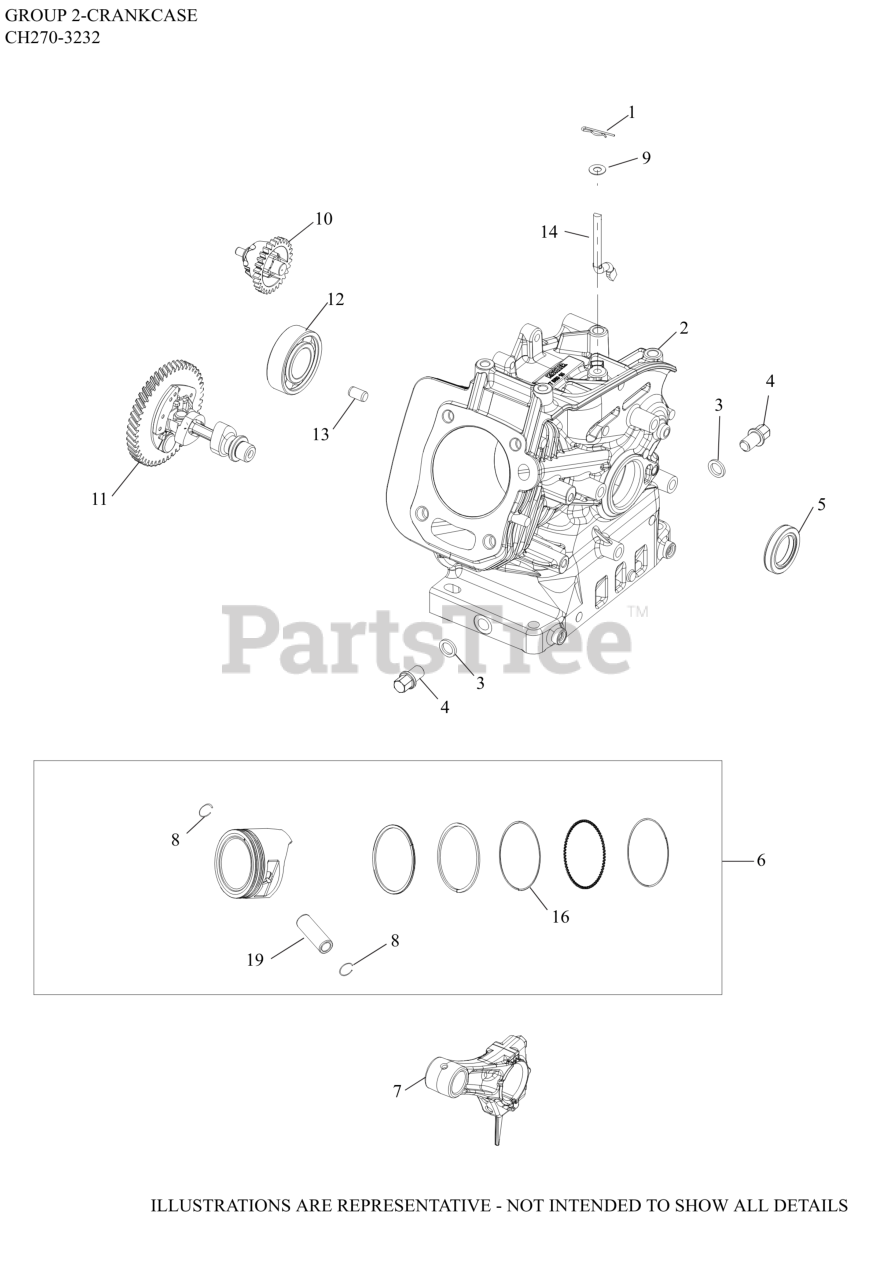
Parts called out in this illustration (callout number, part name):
1	CLIP, GOVERNOR ARM
2	CRANKCASE
3	WASHER, DRAIN PLUG - (#1846801S)
4	KIT, DRAIN PLUG
5	SEAL, OIL
6	KIT, PISTON (STD)
7	ROD, CONNECTING ASSEMBLY
8	RETAINER, PISTON PIN
9	WASHER, FLAT (13MM OD)
10	GOVERNOR ASSEMBLY
11	CAMSHAFT ASSEMBLY
12	BEARING, BALL
13	PIN, DOWEL
14	SHAFT, GOVERNOR CROSS
19	PIN, PISTON
